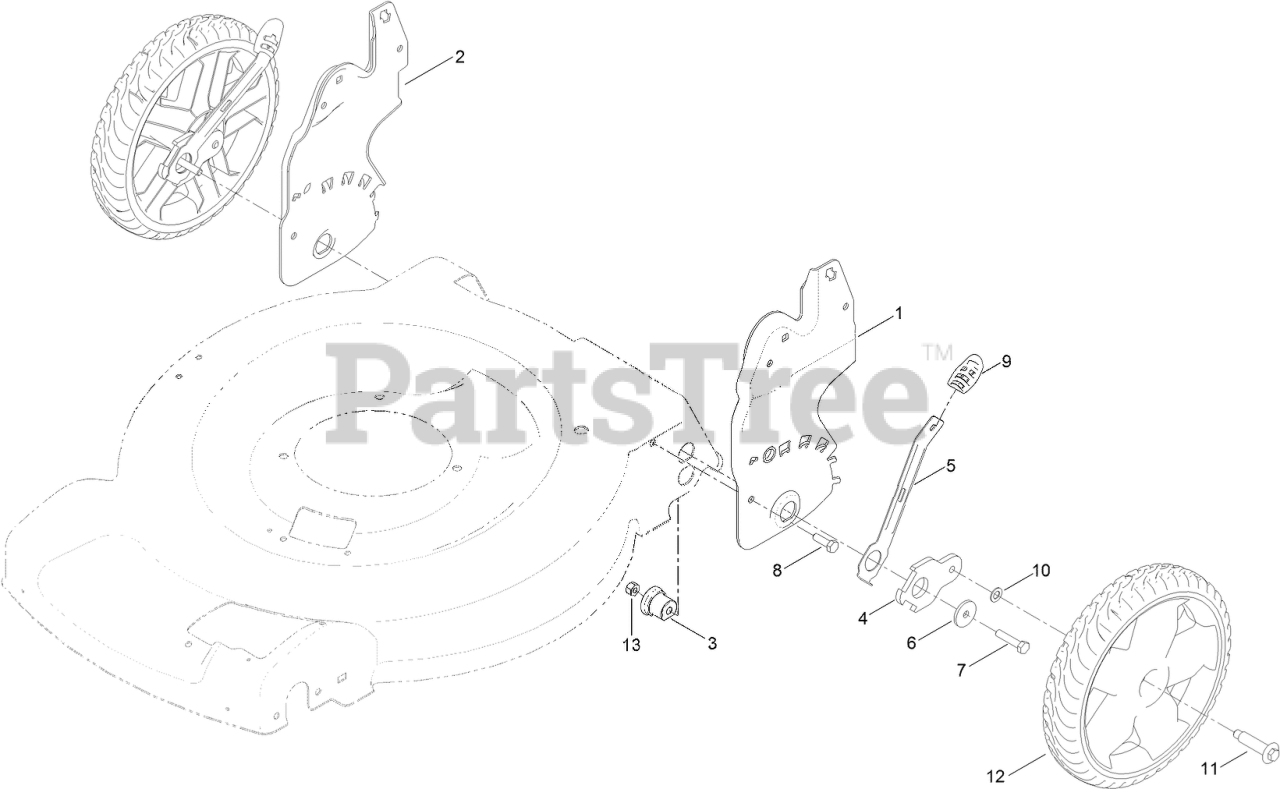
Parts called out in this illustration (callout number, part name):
1	PLATE-HOC, LH
2	PLATE-HOC, RH
3	BUSHING-MOUNT, HOC
4	ARM-PIVOT, REAR
5	ARM-SPRING, REAR
6	Washer-Flat
7	SCREW-HH
8	SCREW-HH
9	Knob-Lever, HOC
10	WASHER
11	BOLT-SHOULDER
12	11 INCH WHEEL ASM
13	NUT-LOCK, NI
